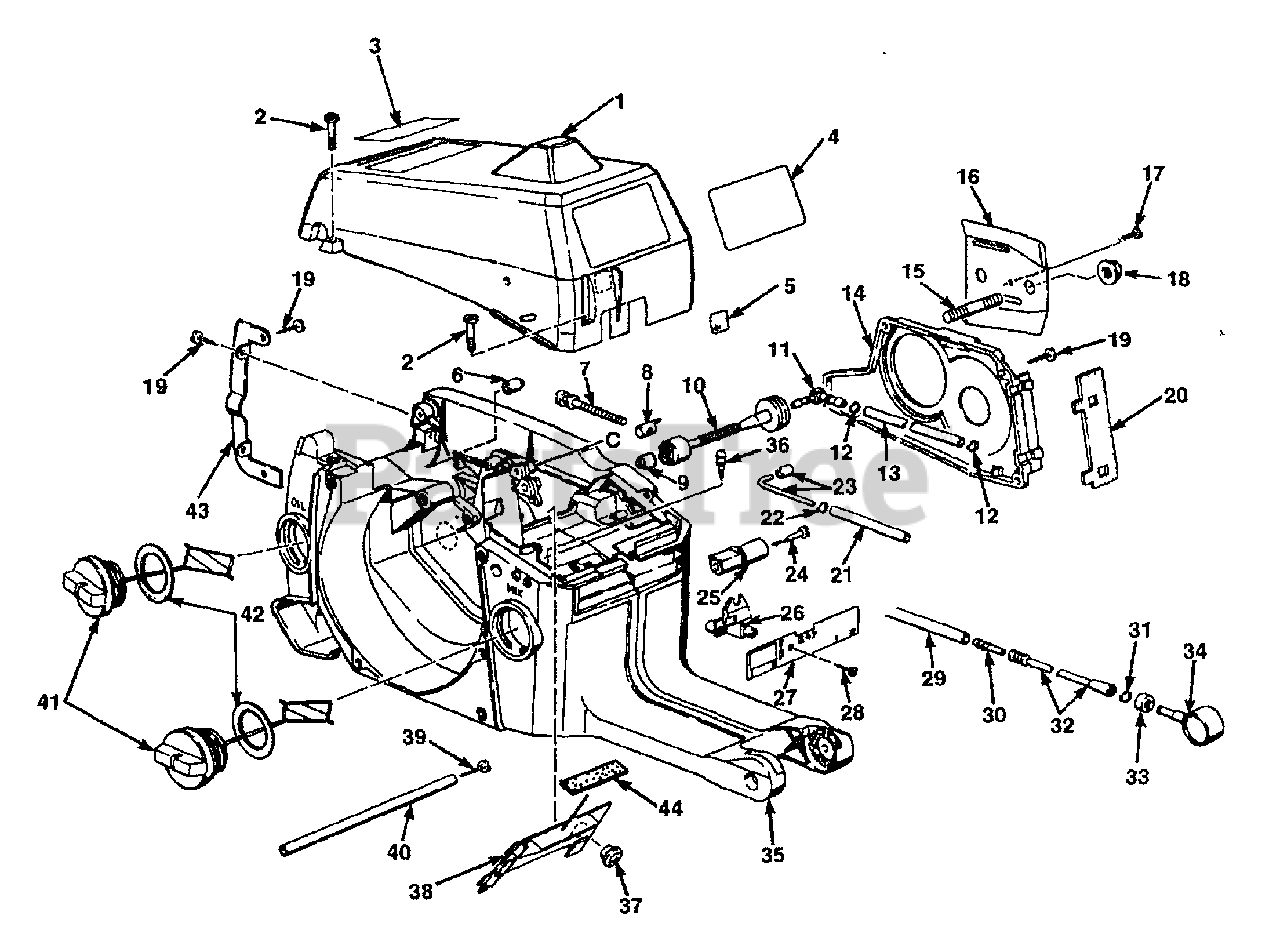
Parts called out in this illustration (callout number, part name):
1	COVER-Cylinder
3	DECAL-Safety instruction
4	DECAL-(290)
5	DECAL-Choke
6	VALVE-Check
7	SCREW-Guide bar adjusting
8	PIN-Guide bar adjusting
9	STRAINER-Oil
10	TUBE-Oil
11	FITTING-Elbow
12	CLAMP-Wire
13	TUBING-Rubber (oil line) 3"
14	COVER-Oil pump
15	STUD-Guide bar
16	PLATE-Guide bar
17	SCREW-(3.5 x 6.5)
18	NUT-W/washer
19	SCREW-(4 x 13)
20	PROTECTOR-Engine housing
21	TUBING-Rubber (oil line) 7 1/2"
22	CLAMP-Wire
23	OIL TUBE KIT
24	SCREW (4.2 x 32)
25	CHAIN STOP
26	SUPPORT-Choke lever
27	PLATE-Switch
28	SCREW (2.9 x 9.5)
29	TUBING-Rubber (1 1/4")
30	FITTING-Hose
31	CLAMP-Wire
32	LINE-Fuel pick-up
33	WEIGHT-Fuel pick-up
34	FUEL FILTER ASSEMBLY
35	ENGINE HOUSING
36	FITTING-Tube
37	PLUG-Baffle
38	BAFFLE-Cylinder
39	SCREW (3 1/2 x 19)
40	TUBING-Rubber (vent) 8"
41	CAP-Oil & Fuel w/retainer
42	GASKET-Oil & Fuel
43	PLATE-Bumper
44	STRIP-Felt
